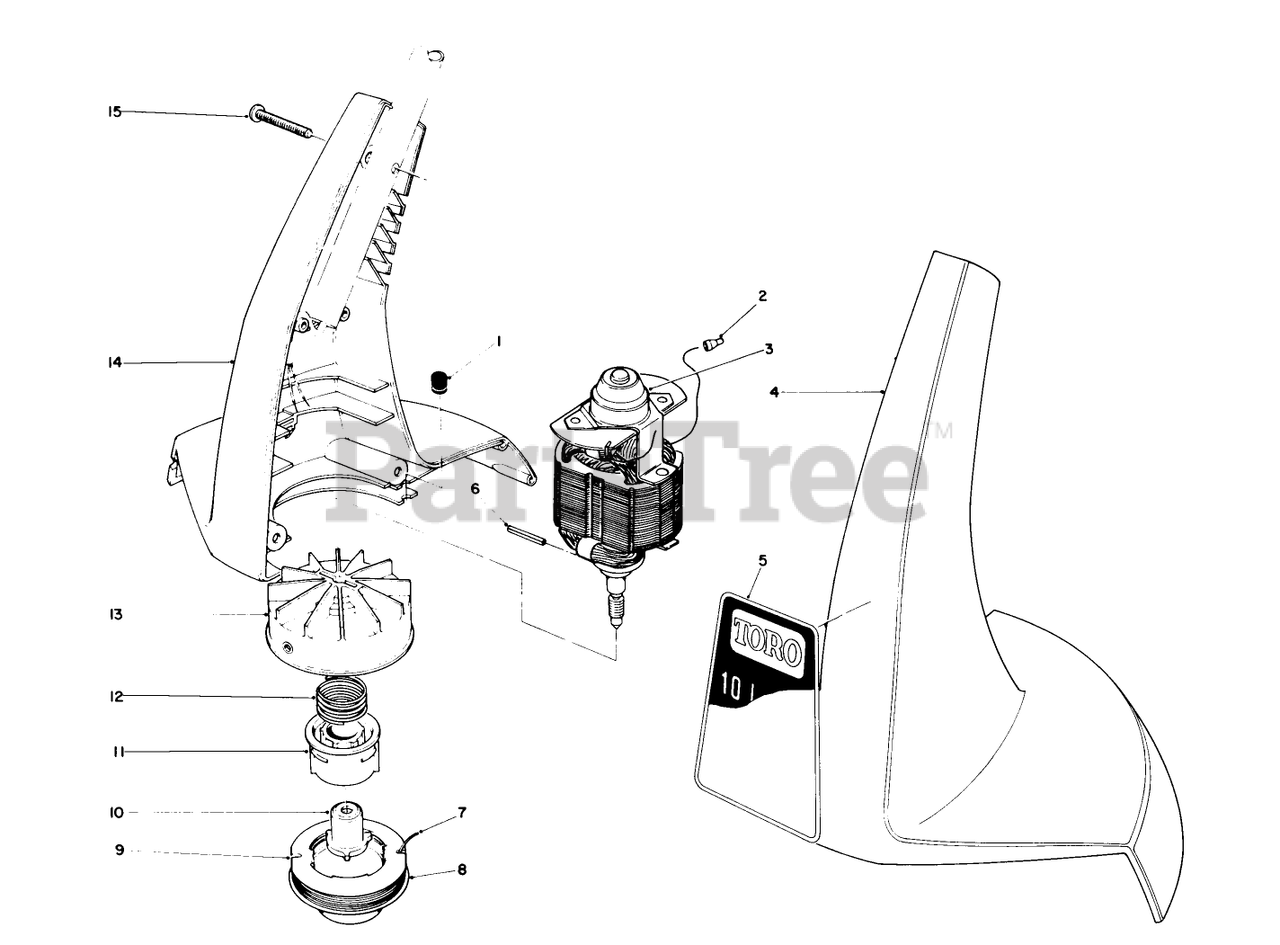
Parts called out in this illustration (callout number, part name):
1	GROMMET
2	CONNECTOR WIRE JOINT
3	Motor
4	Housing-L.H.
5	DECAL, 10" TRIMMER
6	COIL PIN
7	Line-Cutting (30- .05 Dia.)
8	SPOOL CAP
9	Prewound Spool Cap
10	DRIVER DETENT
11	CORE - SPOOL
12	SPRING-COMPRESSION
13	FAN HUB ASM
14	Housing Assembly-R.H.(Incl. Ref. #16 & 17)
15	Capscrew
16	Rivet
17	Blade-Knife
